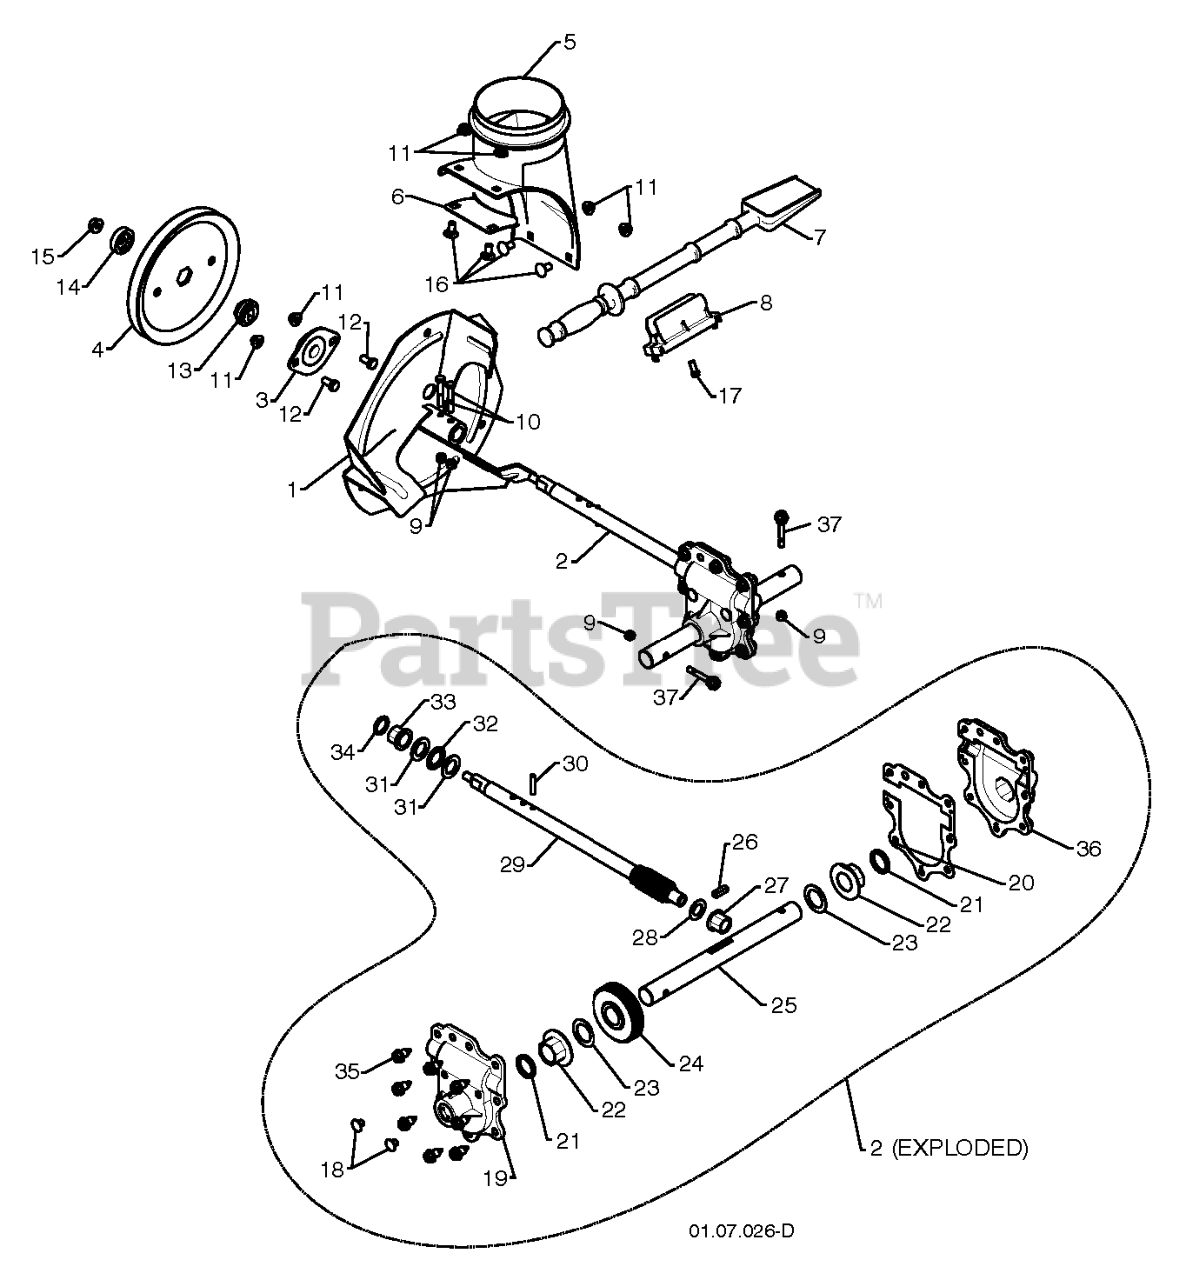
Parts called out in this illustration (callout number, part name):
1	IMPELLER ASSY
2	GEARBOX.ASM.AUGER.D-SHAFT
3	BEARING FLANGE
4	PULLEY.FLANGE.IMPELLER
5	BASE.DISCHARGE.CHUTE
6	BRACKET, CORNER DISCHARGE
7	CLEAN OUT TOOL
8	CLIP.CLEANOUT.TOOL
9	LOCKNUT.NYLOC.1/4-20
10	SCREW.HEX.HD1/4-20X
11	NUTNYLOK.FLRANGE.5/16-18
12	BOLT, HEX HEAD 5/16-18
13	HUB.IMP.PULLEY.D-SHAFT
14	SLEEVE.IMP.PULLEY.D-SHAFT
15	NUT LOCK FLG 3/8-16 UNC
16	BOLT.CARRIAGE.5/16-18X
17	SCREW.HWH.13-16-5.8.BZP
18	CASE PLUG
19	GEAR.BOX.COVER.RIGHT.SIDE
20	GASKET.GEAR.BOX
21	OIL SEAL
22	FLANGE BUSHING-1"
23	WASHER TRUST 1"
24	WORM GEAR
25	AUGER SHAFT
26	KEY, SQUARE 1/4 X .875
27	FLANGE BUSHING-5/8
28	WASHER, THRUST 5/8
29	SHAFT.IMPELLER.D-SHAFT
30	PIN, ROLL 3/16 X 1-1/8
31	WASHER, THRUST 3/4
32	BEARING TRUST 3/4 NTA-1220
33	BUSHING, FLANGE 3/4
35	HEX SCREW-5/16 X 3/4
36	GEAR.BOX.COVER.LEFT.SIDE
37	BOLT.SHOULDER.SHEAR.1/4-20.
